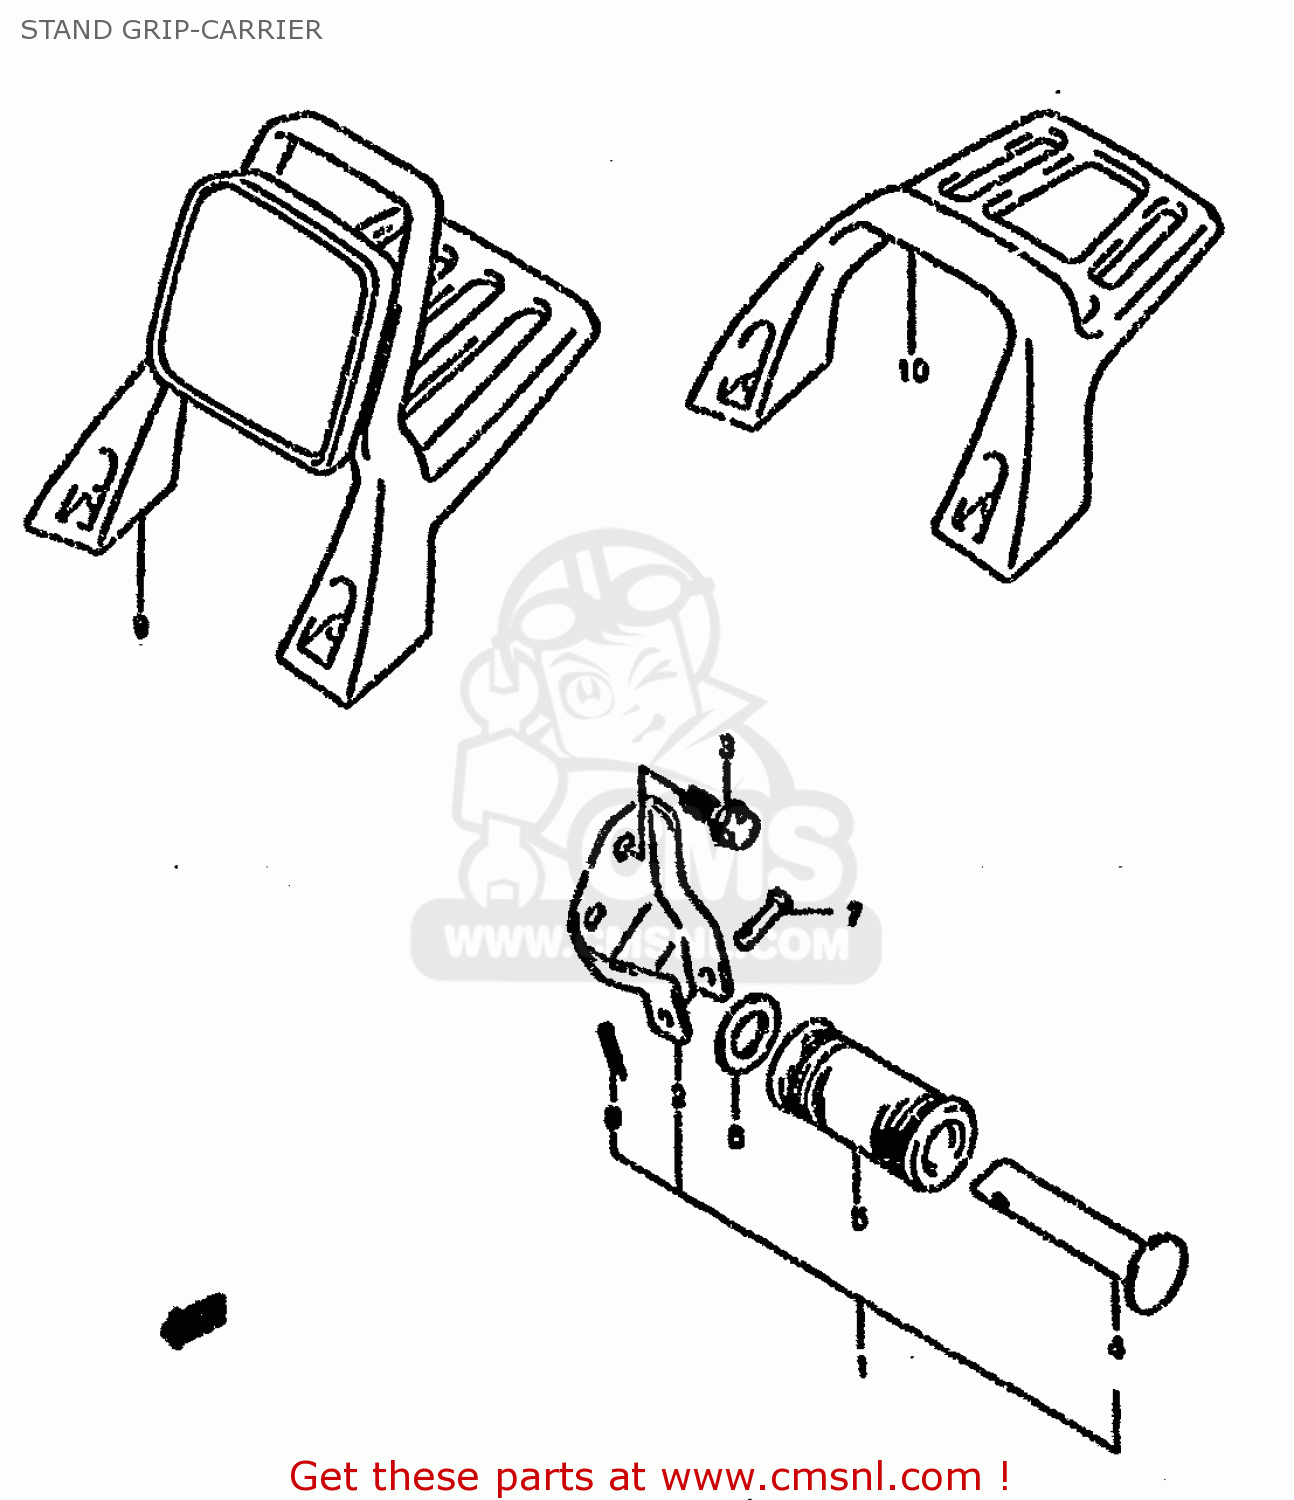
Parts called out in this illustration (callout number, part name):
1	GRIP SET,CTR STAND
2	HOLDER COMP,CENTER STAND
3	BOLT
4	BAR,PILLION FOOTREST
5	RUBBER,STAND GRIOP (OPT)
6	WASHER (19.5X32X2)
7	PIN
8	PIN
9	CARRIER SET,SUPPORT
10	CARRIER SET,SP
